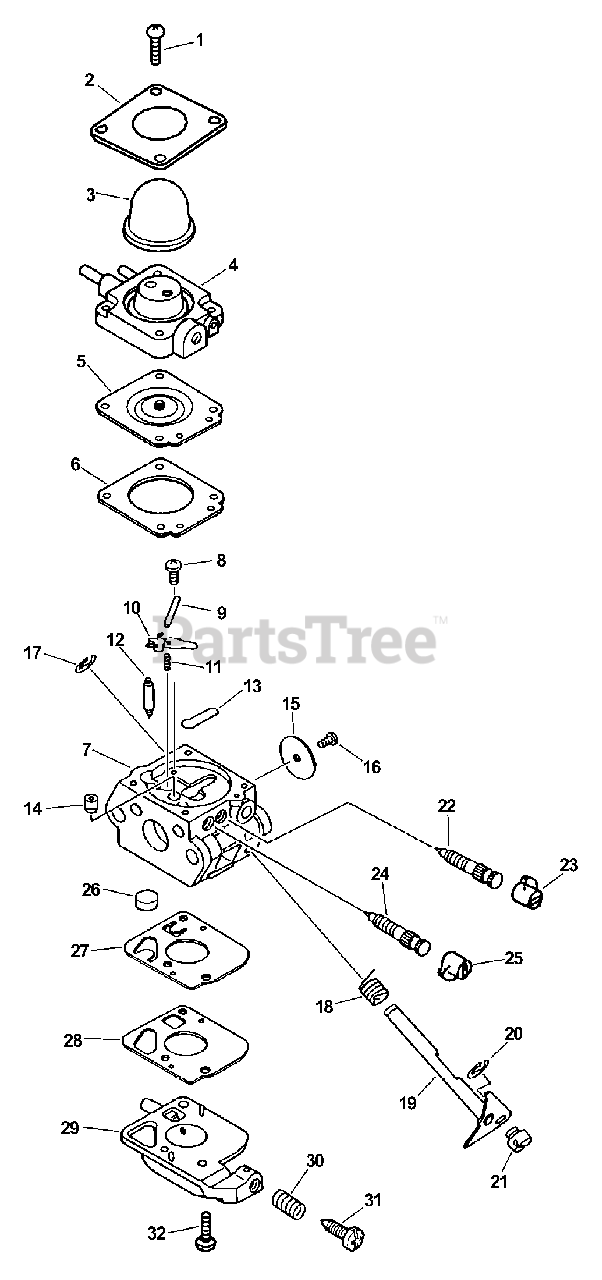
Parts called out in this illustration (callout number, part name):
1	SCREW, RETAINER
2	RETAINER, PURGE BULB
3	BULB, PURGE
4	BASE, PURGE
5	DIAPHRAGM, METERING
6	GASKET, METERING
7	BODY, CARBURETOR
8	SCREW, METERING LEVER PIN
9	PIN, METERING LEVER
10	LEVER, METERING
11	SPRING, METERING LEVER
12	VALVE, INLET NEEDLE
13	PLUG, WELCH
14	NOZZLE, CHECK VALVE
15	VALVE, THROTTLE
17	RING, RETAINING
18	SPRING, RETURN
19	SHAFT, THROTTLE
20	RING, RETAINING
22	NEEDLE - LOW SPEED
23	CAP, LIMITER
24	NEEDLE - HIGH SPEED
25	CAP, LIMITER
26	STRAINER
27	DIAPHRAGM, PUMP
28	GASKET, PUMP
29	BASE, PURGE
30	SPRING, IDLE ADJUST
31	SCREW, IDLE ADJUST
32	SCREW, PUMP COVER
